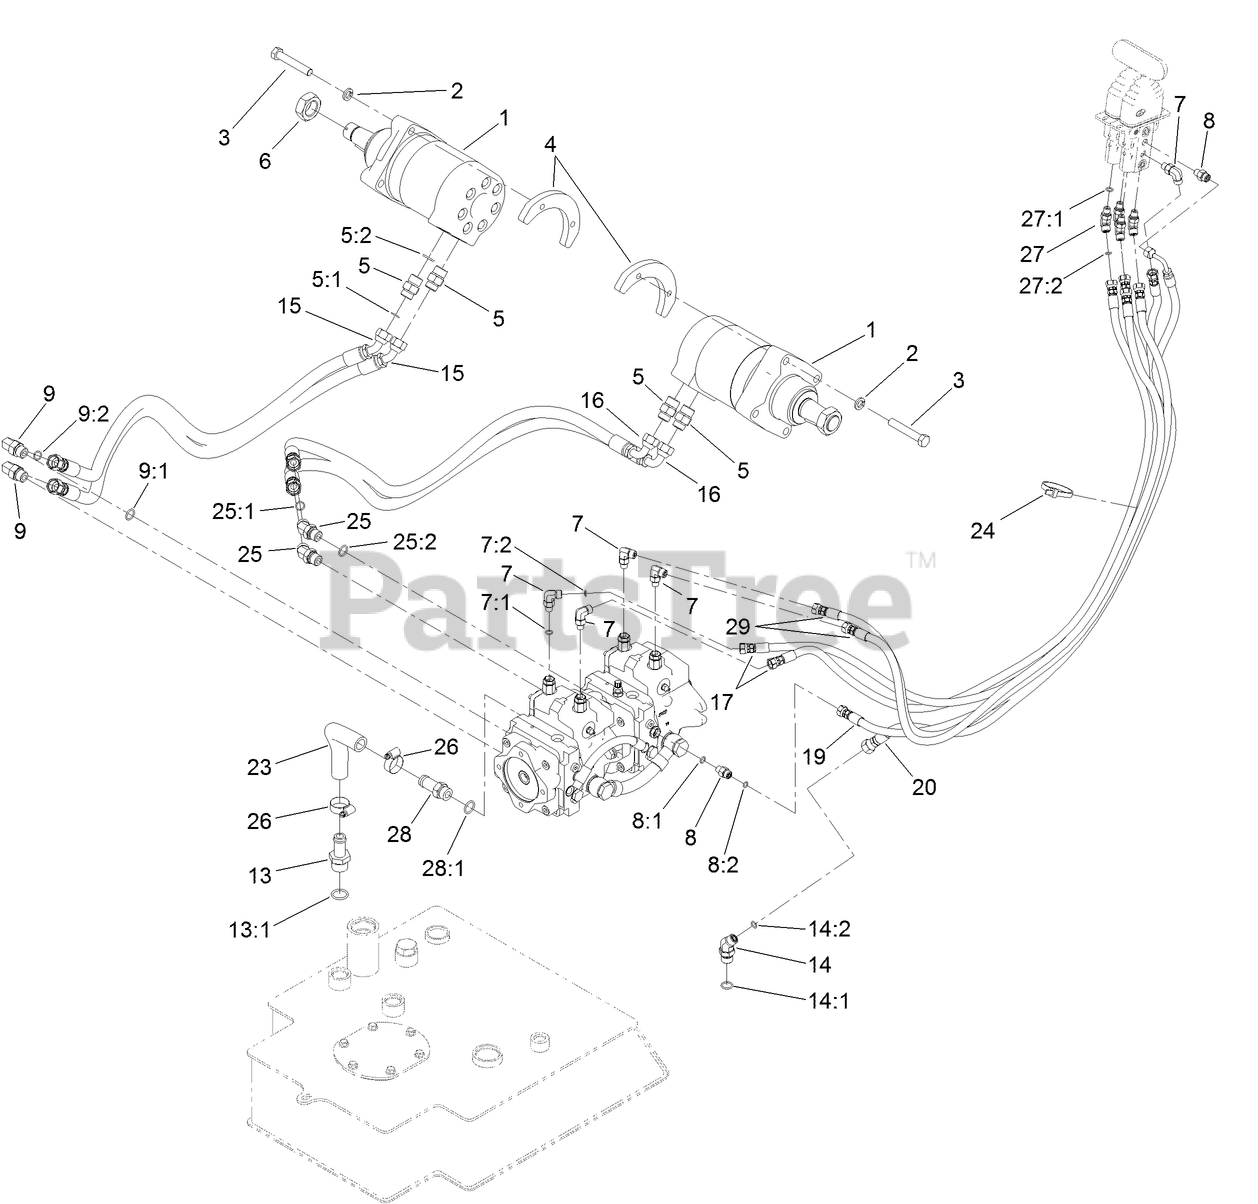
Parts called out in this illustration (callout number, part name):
1	MOTOR-HYD
2	WASHER-LOCK
3	SCREW-HH, TAP
4	PLATE-MOUNTING
5	FITTING-STRAIGHT
5:1	O-RING
5:2	O-RING
6	NUT-HEX
7	FITTING-90 DEG
7:1	O-RING
7:2	O-RING
8	FITTING-STRAIGHT
8:1	O-RING
8:2	O-RING
9	FITTING-ELBOW-90 DEG
9:1	O-RING
9:2	O-RING
13	FITTING-STRAIGHT
13:1	O-RING
14	FITTING-HYD, 45 DEG
14:1	O-RING
14:2	O-RING
15	HOSE-HYD
16	HOSE-HYD
17	HOSE-HYD
19	HOSE-HYD
20	HOSE-RETURN
23	HOSE-RETURN
24	TIE-CABLE
25	FITTING-HYD, 45 DEG
25:1	O-RING
25:2	O-RING
26	CLAMP-HOSE
27	FITTING-HYD, 45 DEG
27:1	O-RING
27:2	O-RING
28	FITTING-STR
28:1	O-RING
29	HOSE-HYD
